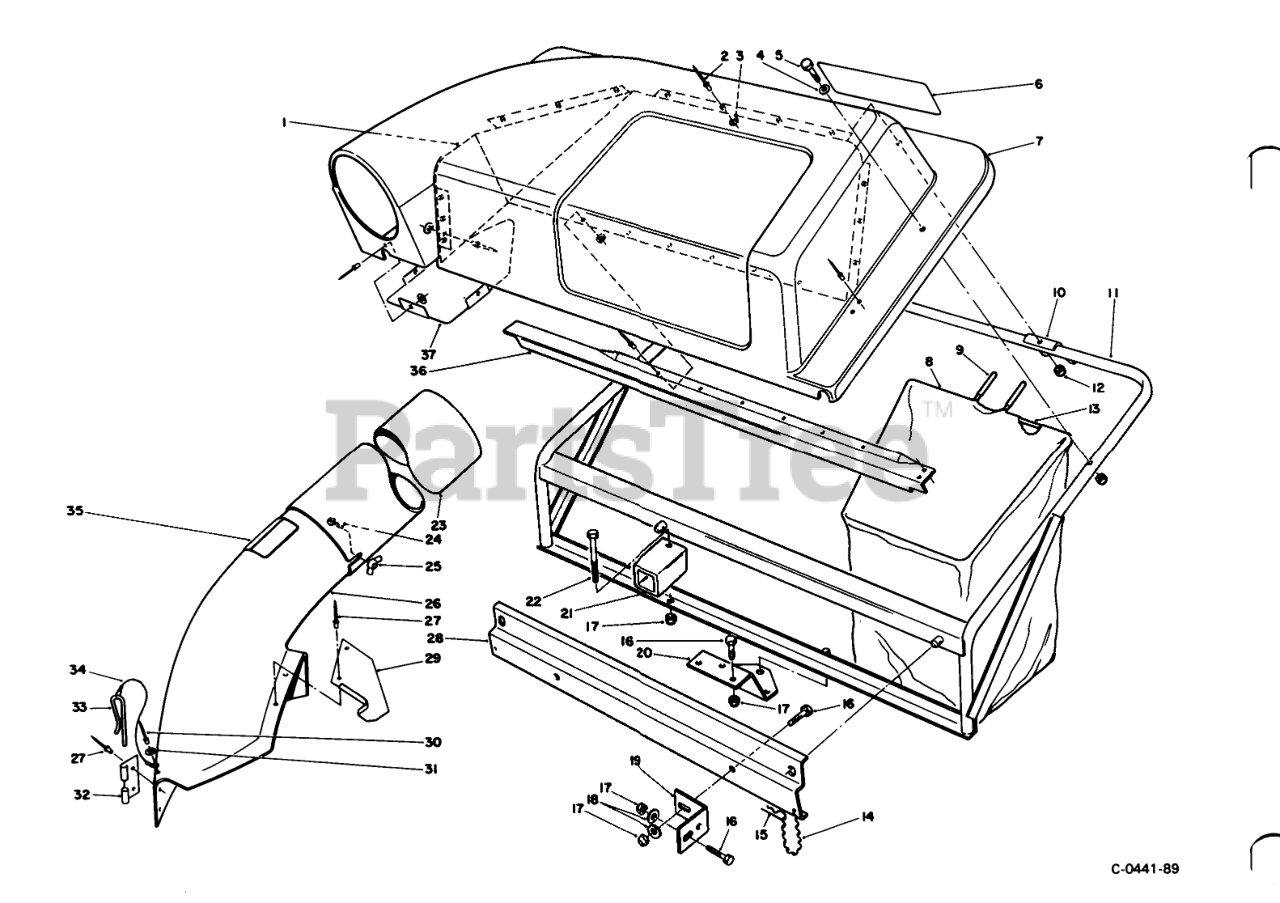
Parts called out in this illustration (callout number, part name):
1	Screen Cover
2	Rivet-Pop
3	WASHER-FLAT
4	WASHER-PLAIN
5	SCREW-HH
6	TWIN BAGGER DECAL
7	Cover
9	GRIP-HANDLE, BAG
10	BAG FRAME BRKT
11	Frame
12	NUT-LOCK, CAP
13	Frame-Bag
14	6-LINK CHAIN W/HOOK
15	PIN-HAIR
16	SCREW-HH
17	NUT-LOCK, NI
18	WASHER-PLAIN
19	MTG BRACKET
20	MTG PLATE B
21	FRAME SUPT TUBE B
22	SCREW-HH
23	TUBE(ROUND&LONG)
24	BOLT-CARR
25	NUT-WING SPECL
26	Chute Assembly (Incl. Ref. #27, 29-35)
27	RIVET-BLIND
28	Bracket Frame Support
29	CHUTE SUPT BRKT
30	RIVET-BLIND
31	WASHER-PLAIN
32	BRACKET-MOUNTING, CHUTE
33	PIN-LOCKING, CHUTE
34	LANYARD
35	DECAL-DANGER
36	SCREEN SUPT BRKT B
37	Shield Cover
